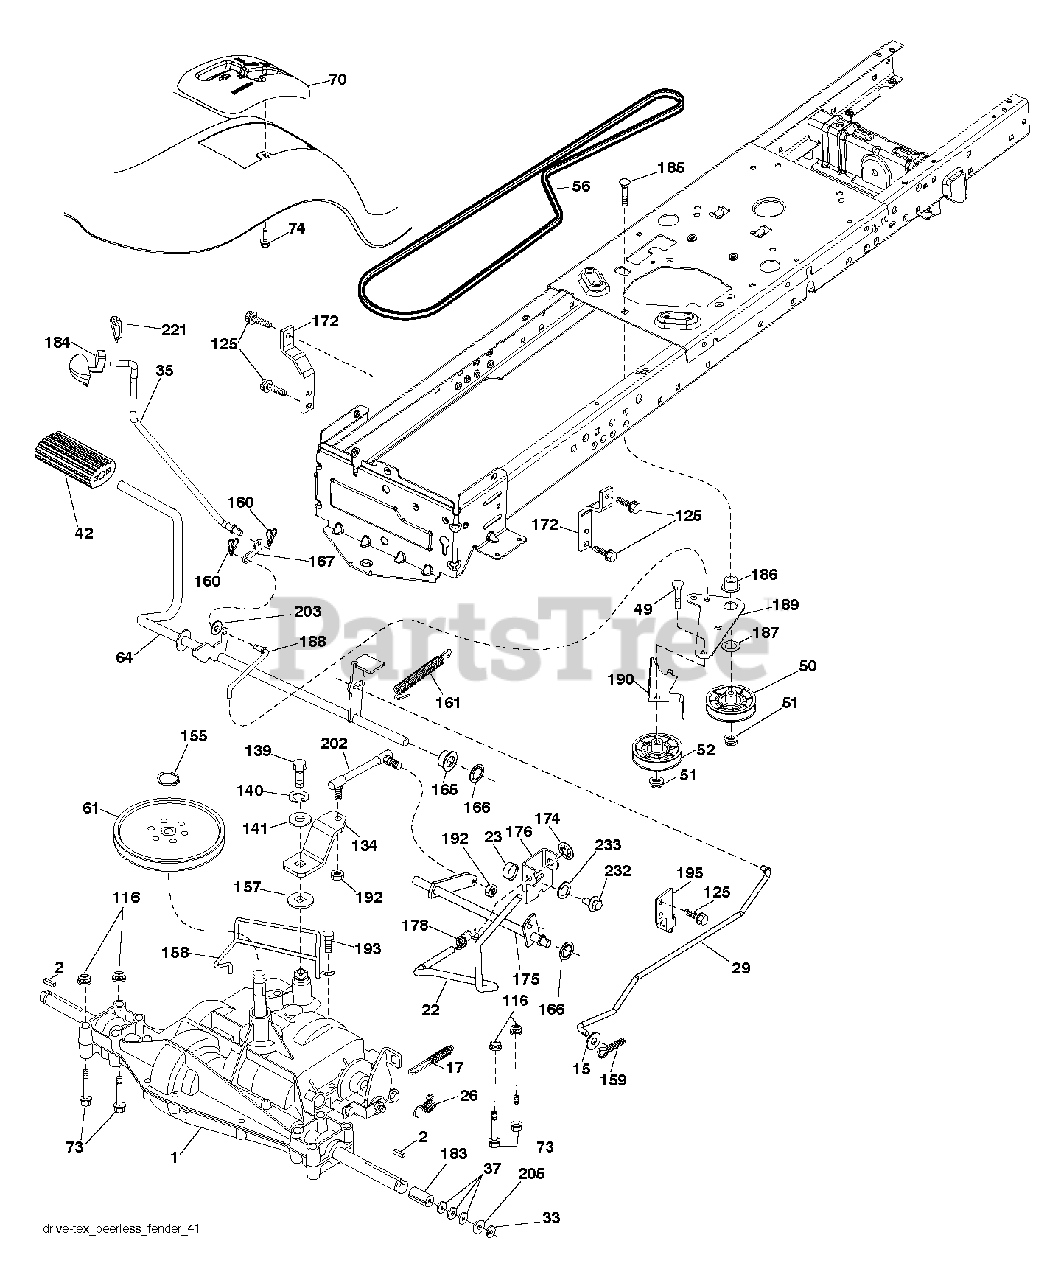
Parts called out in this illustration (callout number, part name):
2	SQUARE KEY
17	SPRING.BRAKE.PEERLESS.TEX
22	ROD.SHIFT.FENDER.TLT.2006
23	KNOB T (1/2-HOLE)
26	SPRING.BRAKE.RTN.GR.DR
29	ROD.BRAKE.PEERLESS
33	E-RING LT
35	ROD.BRAKE.PARKING.LT.T
49	BOLT
50	IDLER.FLAT.910.OFFSET
51	NUT LOCK FLG 3/8-16 UNC
52	IDLER.V-GROOVE.910.OFFSET
56	V-BELT.TRACTOR.DRIVE.P
61	PULLEY TRANS
64	SHAFT.ASM.PEDAL.BRAKE.
70	CONSOLE.SHIFT.STL.6SP.BLACK.T
74	SCREW.HI-LO.CONSOLE
116	NUT LOCK HEX FLANGE 5/16-18
125	SCREW
134	ARM SHIFT
139	Bolt, 1/4-20 unf Grade 8 w/Patch
140	LOCKWASHER
141	WASHER LT
155	RETAINING RING LT
157	WASH-SHFT PLT LT
158	KEEPER.PMS.18/20.D4365
159	COTTER PIN
160	RETAINER CLIP
161	SPRING, RETURN LT
165	BUSHING.SHAFT.BRAKE.HAND
166	NUT.PUSH.625
167	LATCH.BRAKE.SPRING
172	STRAP.TRQ.LH.GEAR.DRIV
174	NUT.PUSH.500.2006
175	SHAFT ASM SHIFT
176	ARM.CLEVIS.ROD.SHIFT
178	SPRING.SHIFT.GT2006
183	SPACER AXLE
184	BOOT.STEERING.LT.TEX.P/L.418
186	SPACER.RETAINER
187	WASHER 12/32X2X10GA
188	LINK.CLUTCH.GROUND.DRIVE
189	BELLCRANK.GROUND.DRIVE.TEX.
190	KEEPER.BELLCRANK.DRIVE
192	NUT LOCK CENTER 1/4 -28 FNTHD
193	SCREW 5/16"
195	BRKT.ROD.BRAKE.PEERLES
202	LINK.SHIFT.PMST.18" (SPG1286)
203	WASHER
221	RETAINER.SPRING.CLIP.H
232	BOLT FIN HEX 7/16-14 X 1
233	WASHER SERRATED
